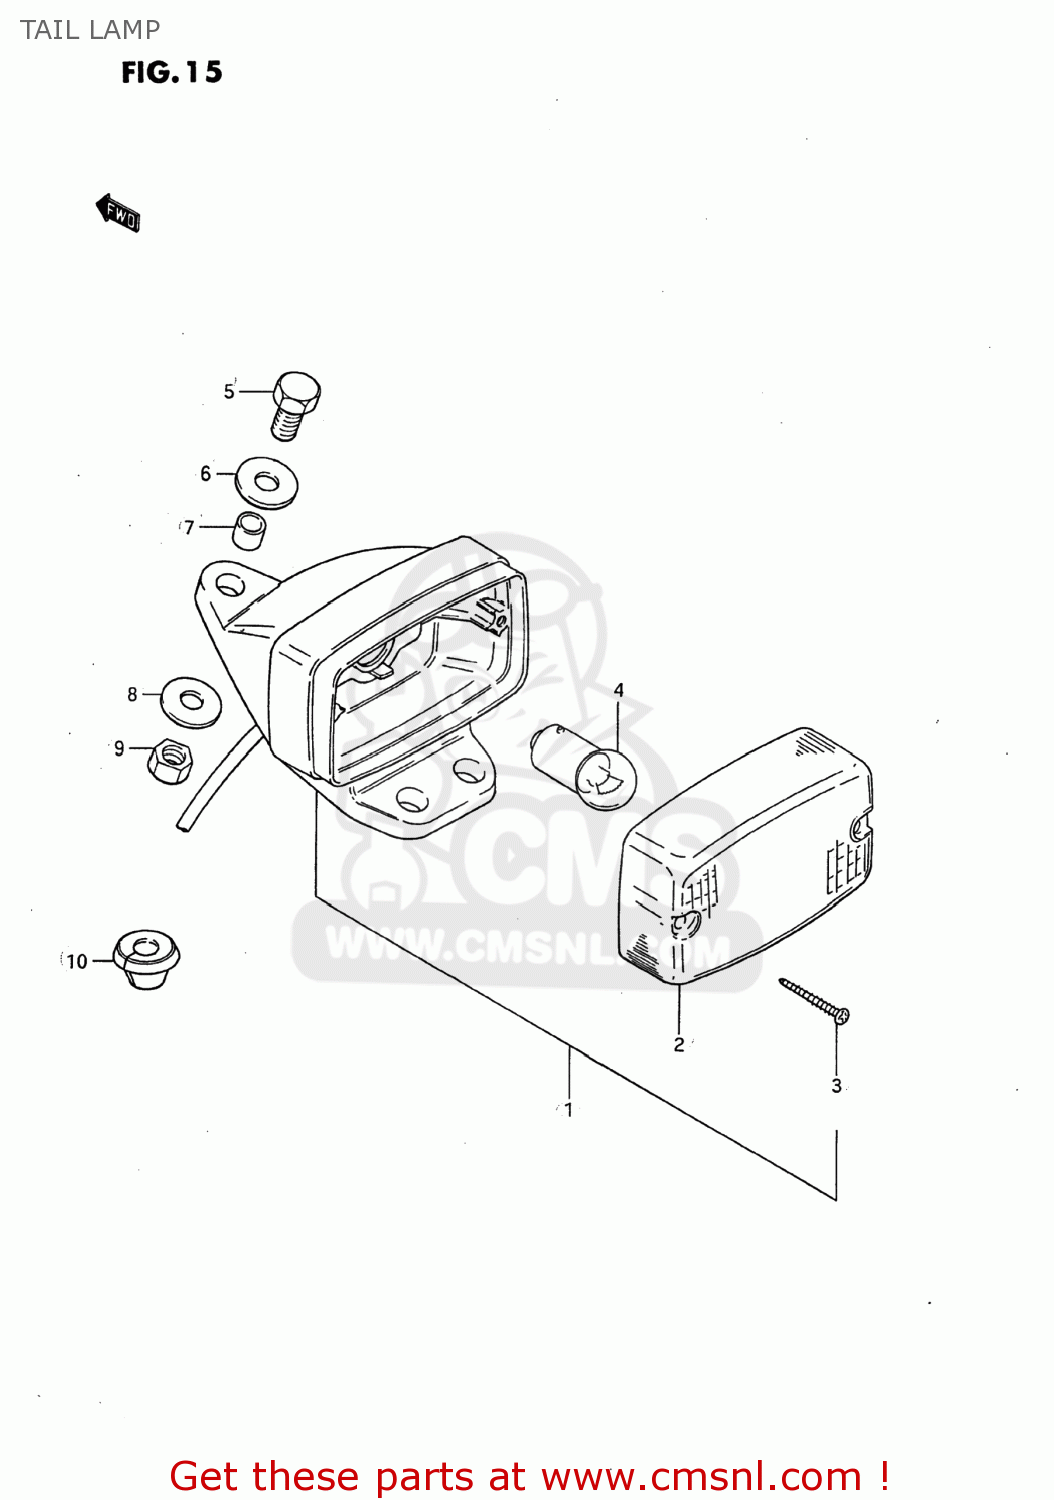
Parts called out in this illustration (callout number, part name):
1	LAMP ASSY,TAIL
2	LENS
3	SCREW
4	BULB(6V5W,TOKAI DENSO)
5	BOLT
6	WASHER
7	SPACER (6.1X9X9)
8	WASHER
9	NUT 6MM
10	GROMMET
